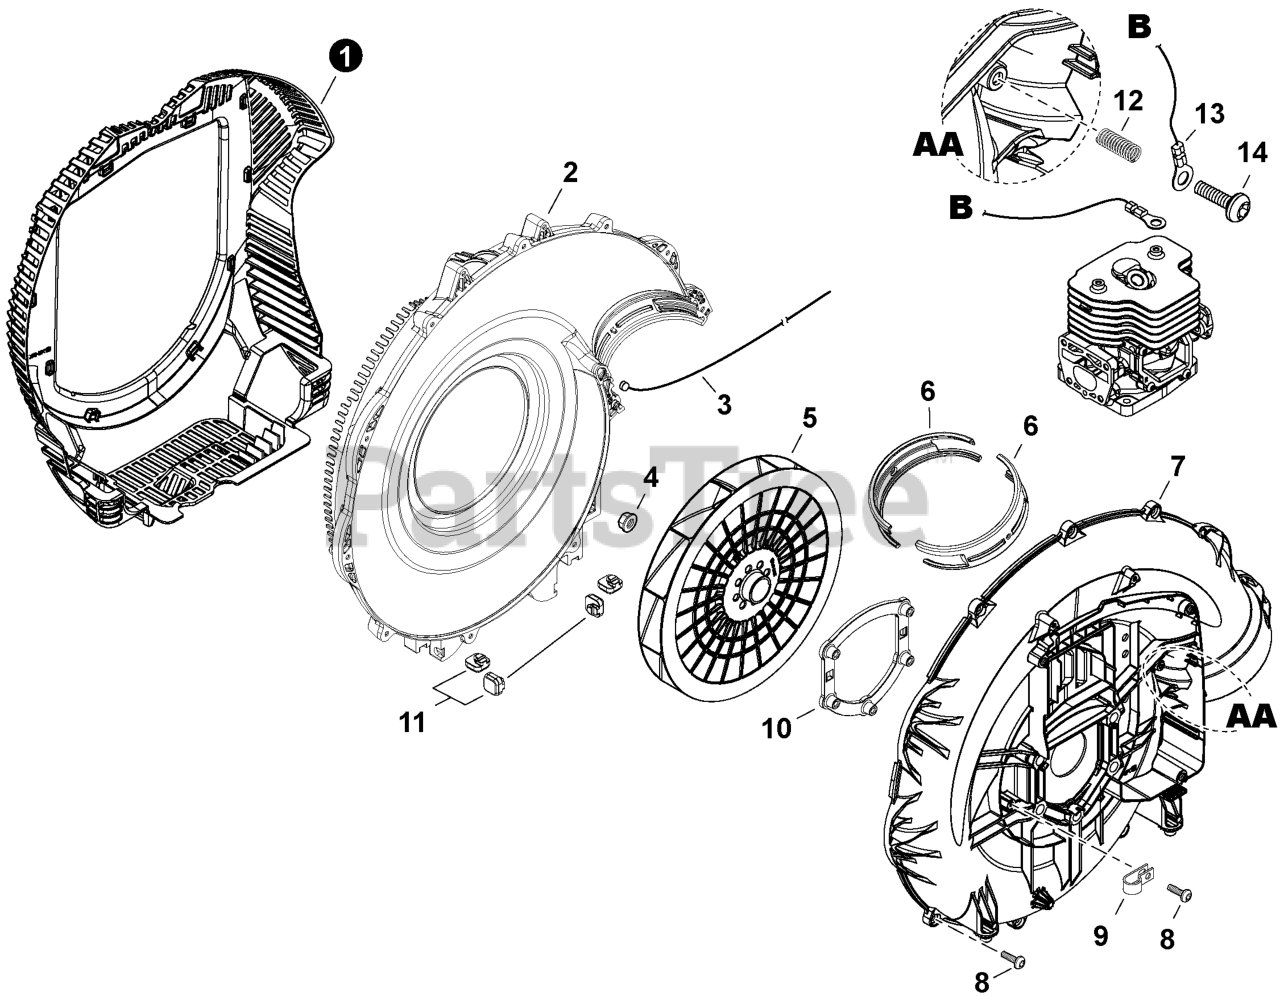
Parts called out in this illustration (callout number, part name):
1	GUARD, DEBRIS
2	COVER, FAN
3	WIRE, ANTI-STATIC
4	NUT, FLANGE 10x1.25
5	FAN, BLOWER
7	CASE, FAN
8	BOLT, TORX 5x20
9	CLIP
10	PLATE, ENGINE
11	CUSHION
12	SPRING, COMPRESSION
14	BOLT, TORX 5x12
